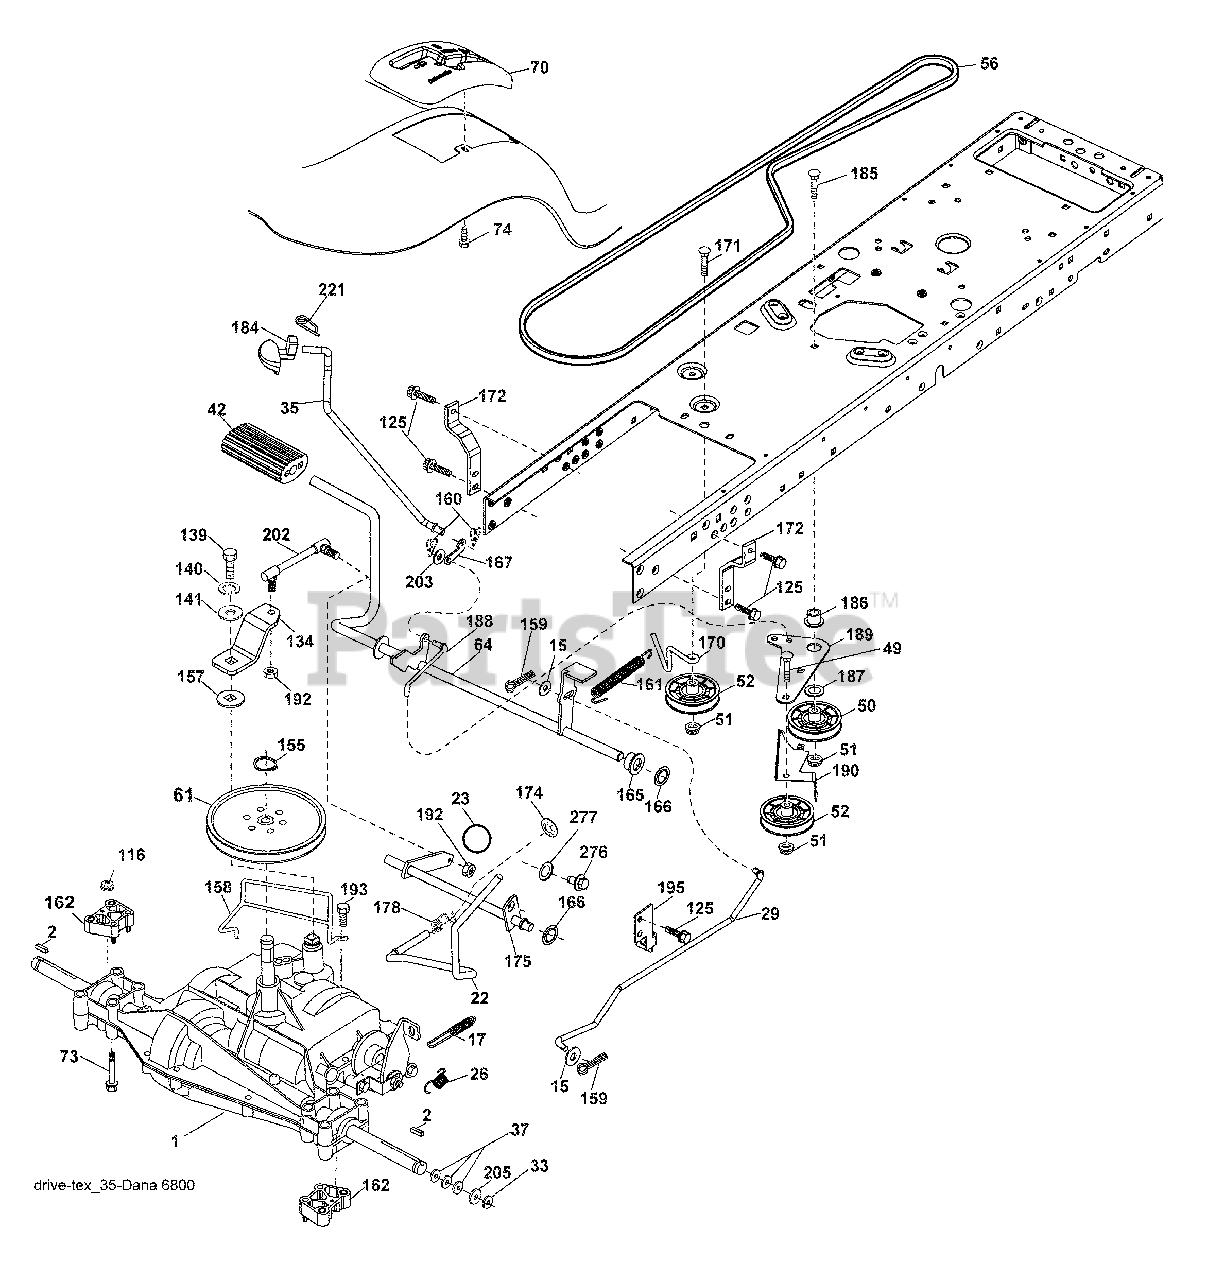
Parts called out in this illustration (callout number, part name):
2	Key Square
15	Washer 13/32 x 13/16 x 16 Ga.
17	Spring, Brake
26	Spring Brake Return
29	Rod, Brake
35	Rod, Brake, Park
37	Washer 25/32 x 1-1/4 x 16 Ga.
42	Cover, Foot Pedal
50	Pulley Idler Flat
51	Lock Nut 3/8-16
52	Idler V-Groove 910" Offset
56	V-Belt, Drive
61	Pulley transaxle
64	Shaft Asm. Pedal Brake Control
70	Console
73	Bolt Hex Flghd 5/16-18 x 3.0 Gr. 5
74	Screw 1/4 x 1/2
116	Nut Lock Hex Flange 5/16-18
125	Screw 5/16-18 x 3/4
139	Bolt 1/4-28 unf Gr. 8 w/Patch
140	Washer Lock Hvy Helical 1/
141	Washer 9/32 x 3/4 x 10 Ga.
155	Ring Retainer
157	Washer Plate Shift
158	Belt Keeper
159	Pin Cotter 1/8 x 3/4
160	Retainer Clip
161	Spring, Return, Clutch
162	Spacer Trans.
165	Busing Shaft Brake Hand Control
166	Nut Push .625
167	Latch Brake Parking
170	Keeper Belt Centerspan
172	Strap Torque LH
175	Shaft Asm. Shift
178	Spring Shift
184	Handle Parking
186	Spacer Retainer
187	Washer
188	Link Clutch Ground Drive
189	Bellcrank Ground Drive
190	Keeper Bellcrank Ground Drive
192	Nut Lock Center 1/4-28 Fnthd
193	Screw 5/16-18 x 3/4
195	Bracket Brake Rod
202	Link Transaxle
203	Washer 11/32 x 11/16 x 16 Ga.
205	Washer 25/32 x 1-5/8 16 Ga.
221	Retainer Spring Clip Handle
276	Bolt Fin Hex 7/16-14 x 1 Gr. 5
277	Washer Serrated
